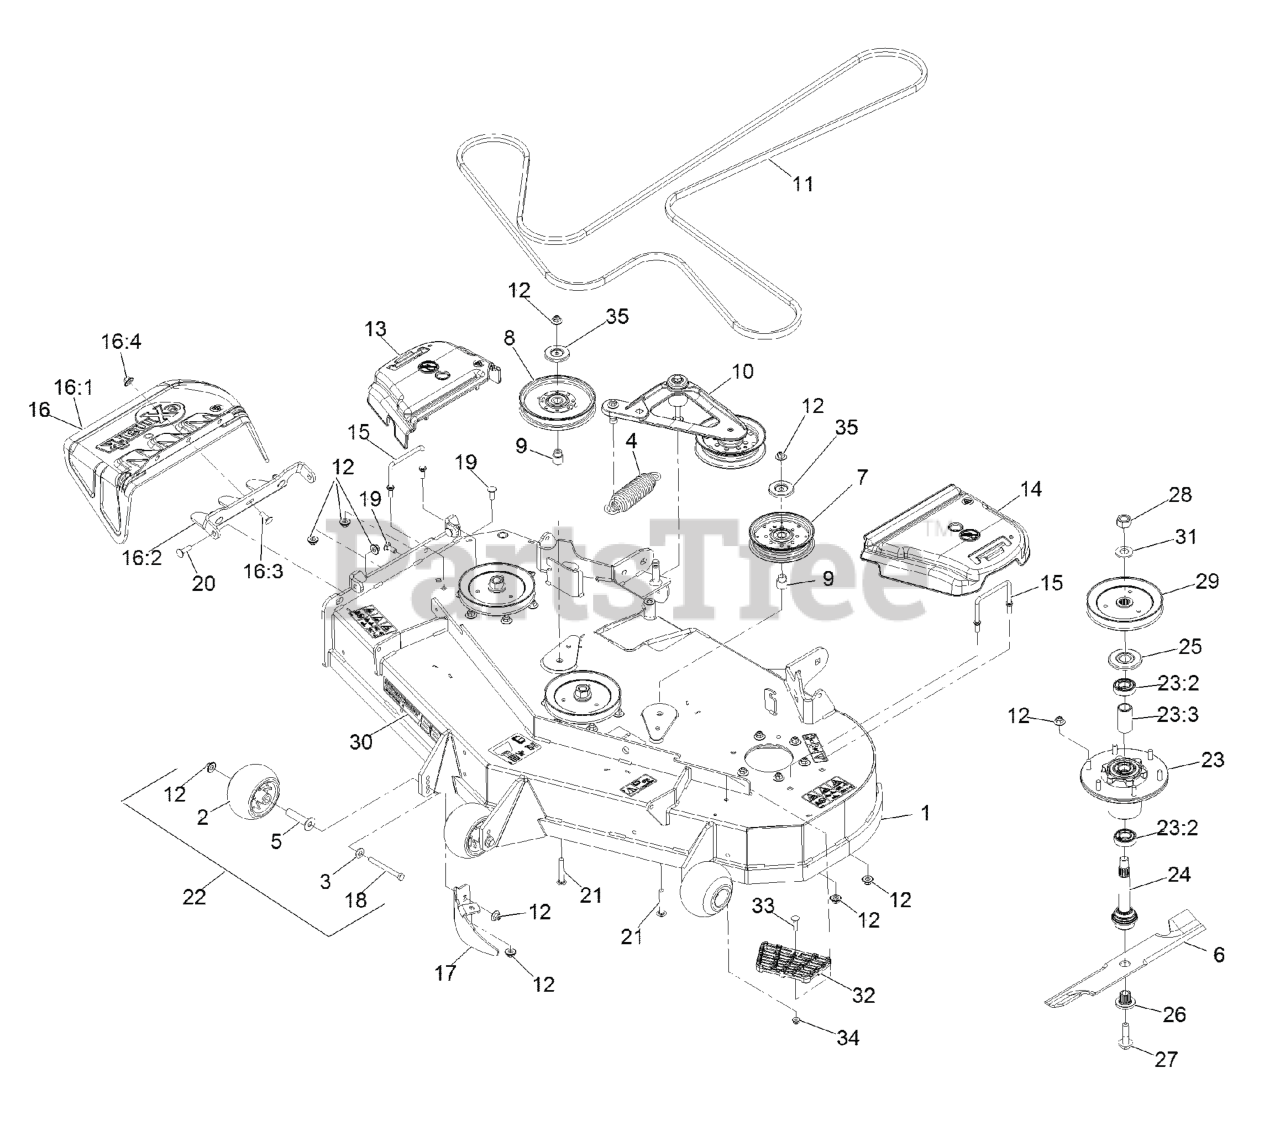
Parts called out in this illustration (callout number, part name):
1	ASM,DECK W/DECALS 48
3	BUSHING-IDLER
4	PULLEY-IDLER, FLAT
5	IDLER-PULLEY
6	SCREW-CARR
7	Nut-Nyloc 3/8-16 Flg
8	DECK IDLER ASM
9	ASM,DISCHARGE CHUTE
9:1	CHUTE,DISCHARGE
9:2	BRACKET,DISCHARGE CHUTE
9:3	SCREW-CARR
9:4	Nut-Nyloc 3/8-16 Flg
10	Bolt-Carriage 3/8-16 X 1 1/4
11	BELT
12	WIREFORM-COVER
13	COVER-BELT, RH
14	COVER-BELT, LH
15	SPRING-EXTENSION
16	BAFFLE-DOGLEG,LZS LZX VT4
17	SCREW-CARR
18	AXLE, ROLLER
19	ROLLER-SCALP, ANTI
20	WASHER-BELLEVILLE
21	SCREW-HH 3/8-16 X 3 3/4 GR 8
22	KIT, ANTI-SCALP ROLLER
23	ASM-CUTTER HSG WITH BEARINGS
23:2	BEARING-BALL
23:3	SPACER-BEARING
24	ASM-SPINDLE AND SEAL
25	GUARD,BEARING TOP .989
26	BUSHING,SPLINED
27	SCREW,SEMS 1/2-20 X 2.19
28	NUT-HEX
29	SHEAVE,BLADE DRIVE 5.90
30	Decal, 484
32	STEP-DECK
33	Bolt-Carriage 5/16-18 X 1 1/4
34	NUT-HF, NI
35	SHIELD-DUST
